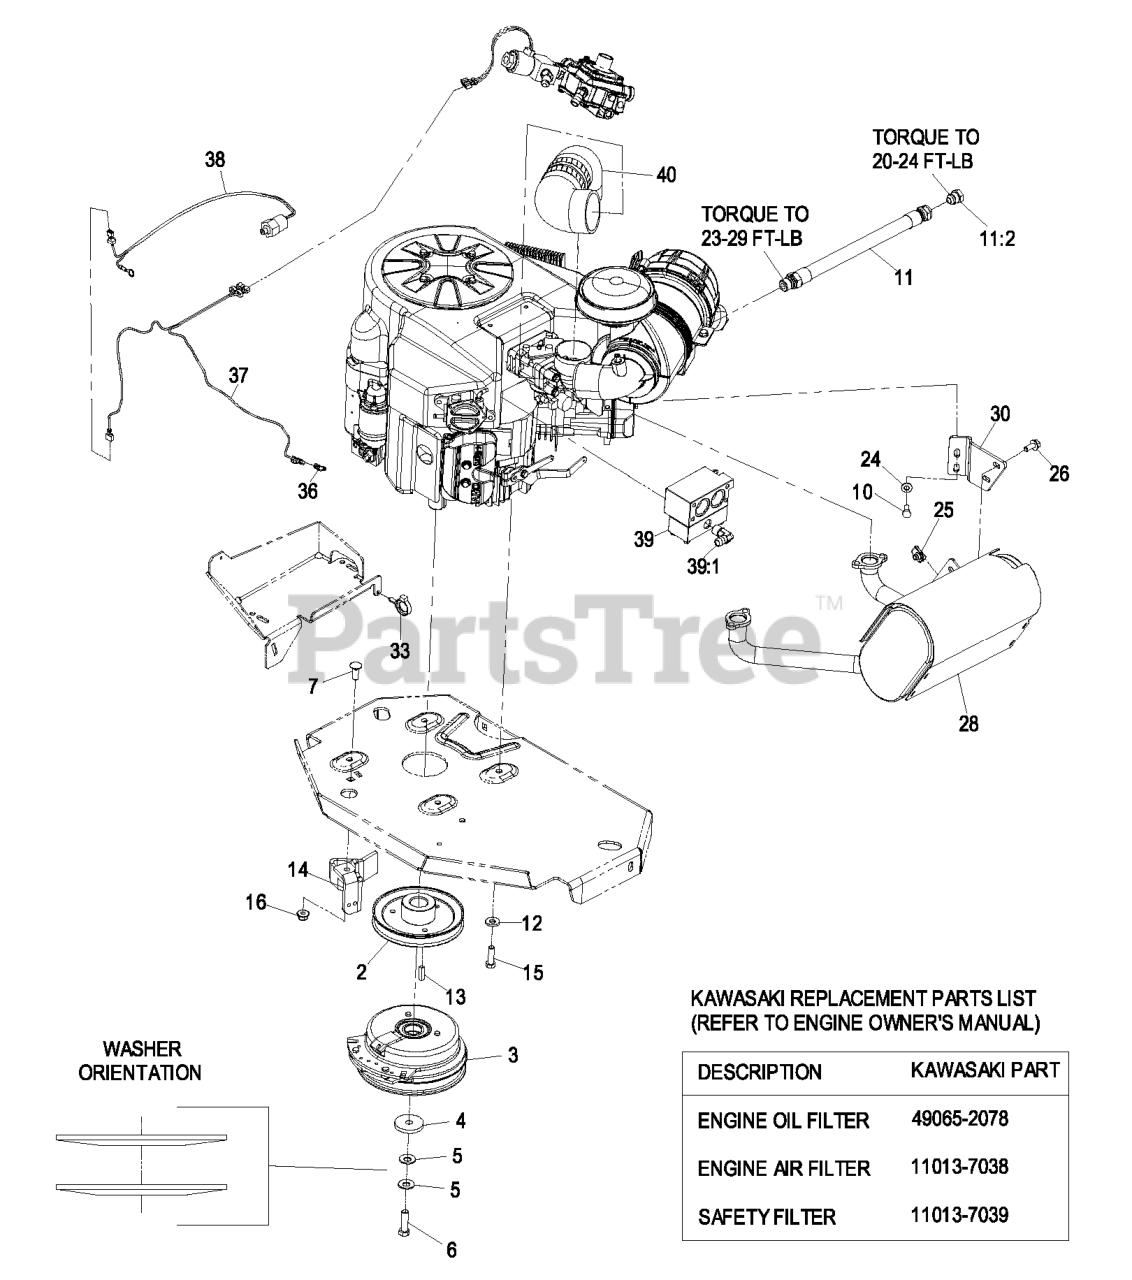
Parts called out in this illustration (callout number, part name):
2	SHEAVE
3	CLUTCH KIT
4	WASHER-CLUTCH
5	WASHER-SPRING
6	SCREW-HH 7/16-20 X 1 1/2 W/LOCTITE
7	SCREW-CARR
10	SCREW-HH
12	WASHER-BELLEVILLE
14	CLUTCH-ANCHOR
15	SCREW-HH
16	NUT-HF, NI
24	WASHER-SPRING
26	SCREW-HHF
28	MUFFLER
30	BRACKET-MUFFLER
33	CLAMP-HOSE
34	AIR INTAKE HOSE ASM
36	TERMINAL-TAB
37	WIRE HARNESS
39	MIXER-LPG
39:1	ELBOW-90 DEG
40	AIR INTAKE HOSE ASM
